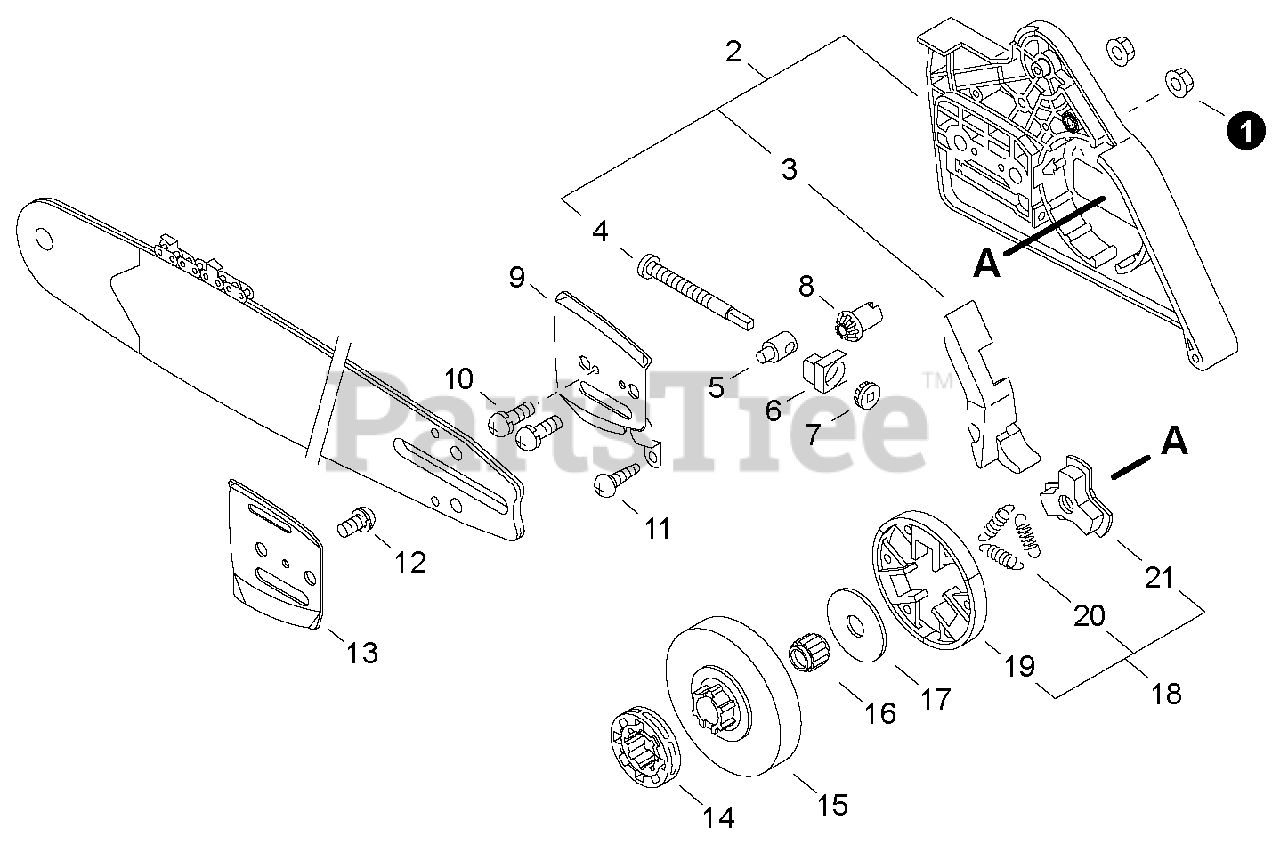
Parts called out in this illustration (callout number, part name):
1	NUT, FLANGE M8×1.25
2	GUARD KIT, SPROCKET
3	CUSHION
4	SCREW, CHAIN TENSION
5	TENSIONER, CHAIN
6	COLLAR 8
7	GEAR, BEVEL
8	GEAR, BEVEL
9	PLATE, GUIDE - OUTER
10	SCREW 3×6
11	SCREW 4×10
12	SCREW 4×8
13	PLATE, GUIDE - INNER
14	SPROCKET, RIM 3/8"×7T
15	DRUM, CLUTCH
16	BEARING, NEEDLE
17	PLATE, CLUTCH
18	CLUTCH ASSY
19	SHOE SET, CLUTCH (3PCS)
20	SPRING, TENSION
21	HUB, CLUTCH
